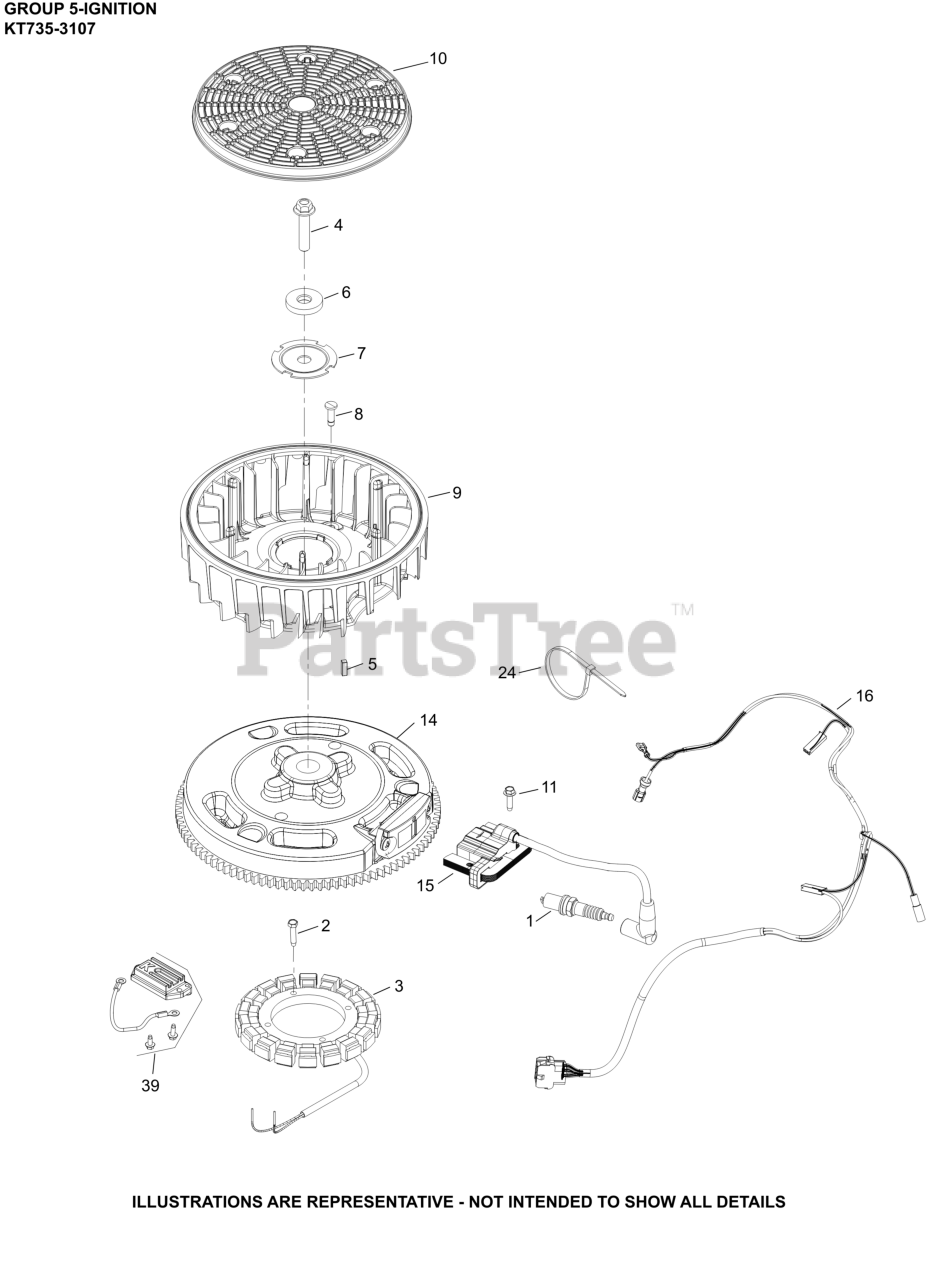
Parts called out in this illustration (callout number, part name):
1	PLUG, SPARK
2	SCREW, THREAD FORMING
3	KIT, 15 / 20 AMP STATOR
4	SCREW, HEX FLANGE
5	KEY, SQUARE
6	WASHER, FLAT
7	PLATE, FAN MOUNTING
8	RETAINER, FLYWHEEL FAN
10	SCREEN, GRASS
11	SCREW, THD FRM-USE 25 086 473-S
14	FLYWHEEL ASSEMBLY
15	MODULE, CDI IGNITION
16	HARNESS, WIRING ASSEMBLY
39	KIT, REGULATOR RECTIFIER
